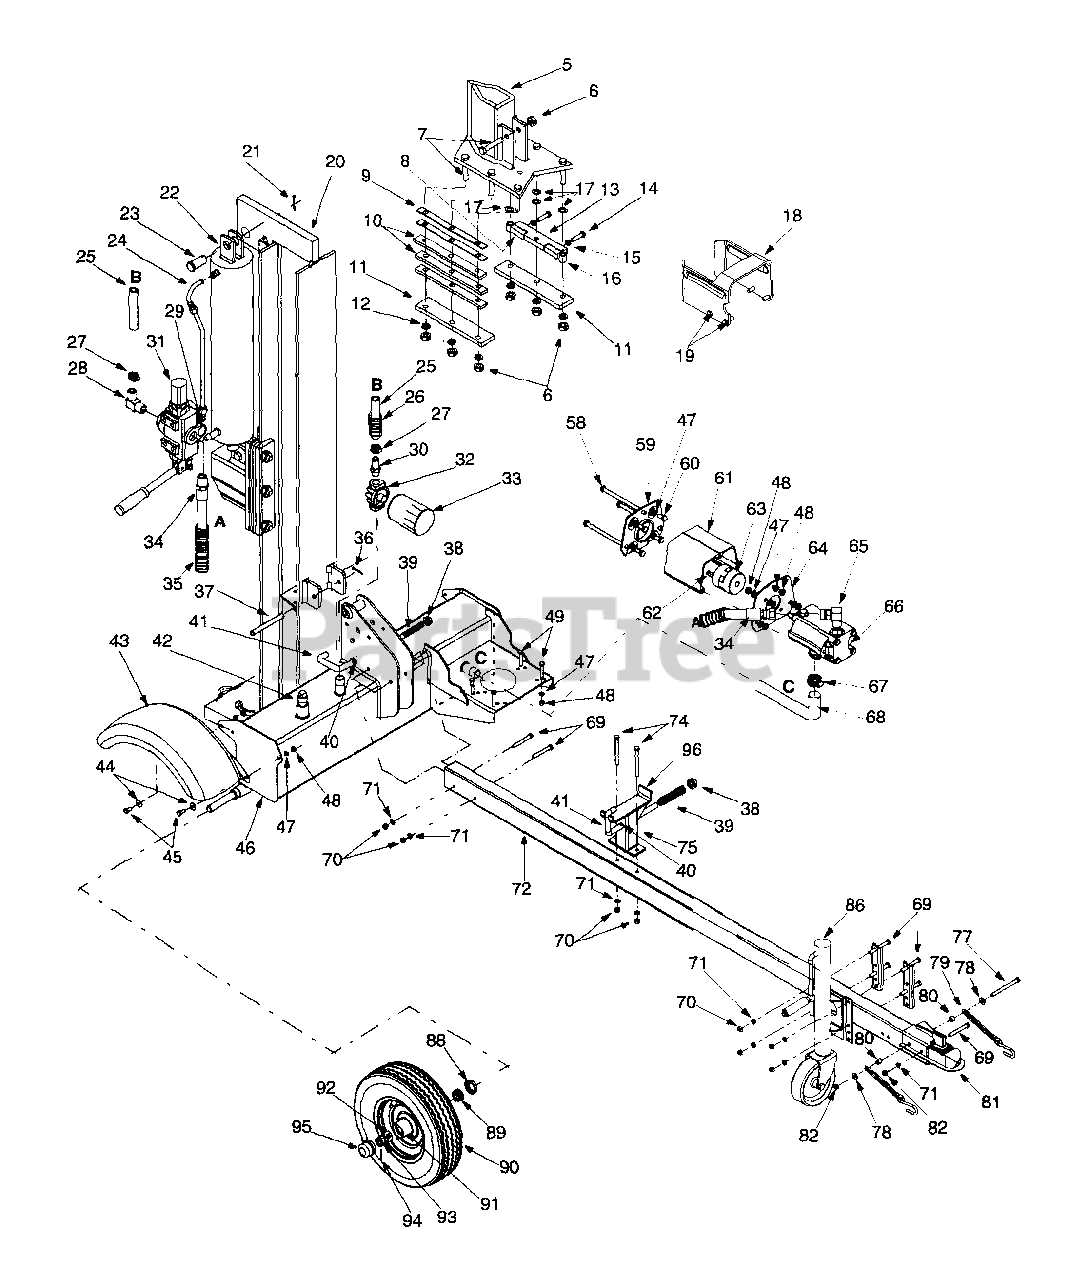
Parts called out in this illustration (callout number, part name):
6	Lock Nut 1/2-20
7	Hex Cap Screw 1/2-20 x 2.75
12	Lock Washer 1/2
14	Hex Cap Screw 3/8-24 x 1.5
15	Hex Jam Nut 3/8-24
16	Spacer
17	Flat Washer.531 x.93 x.090
19	Hex Screw 3/8-16 x 1.0" Gr.5
22	Kit Seal 5.0" for Best Metals cylinder 718-0313
22	Hydraulic Cylinder
22	Kit Seal 5.0" for XINGHUI cylinder 718-0313A
22	Kit Seal 5.0" for ENERGY cylinder 718-0313A
23	Clevis Pin
24	Hydraulic Tube
25	Return Hose 3/4" ID x 44" Lg
26	Hose Guard
27	Hose Clamp 5/8"
28	Return Elbow
29	90 Degree Solid Male Adapter
30	3/4" Hose Adapter
32	Filter Housing
33	Oil Filter
34	High Pressure Hydraulic Hose
35	Hose Guard
36	Cotter Pin 1/8" Dia
37	Hinge Pin 1/2 x 4.8" Lg.
38	Push Cap
39	Comp. Spring 4" Lg.
40	Flat Washer .635 ID x.93 OD
41	Locking Rod
42	Pipe Plug
45	Hex Cap Screw 5/16-24 x.75
48	Hex Nut 5/16-24
49	Hex Cap Screw 5/16-24 x 1.75
58	Hex Screw 5/16-24 x 5.25"
60	Hex Cap Screw 5/16-24
61	Coupling Shield
62	Square Key
63	Flexible Coupling
65	Adapter
66	Gear Pump (16 gpm)
67	Hose Clamp
68	Suction Hose
69	Hex Cap Screw 3/8-16 x 3.0
70	Hex Nut 3/8-16
71	Lock Washer 3/8
74	Hex Cap Screw 3/8-16 x 4.0
77	Hex Cap Screw 3/8-16 x 4.25
78	Flat Washer.385 ID x.870 OD
79	Chain
80	Spacer
81	Hitch Coupler
82	Lock Nut 3/8-16
86	Adjustable Jack Stand
88	Bearing Seal Only
89	Bearing Cone
90	Wheel Asm Comp - Gray
91	Bearing Cup
92	Flat Washer.76" ID x 1.5" OD
93	Slotted Nut 3/4-16
94	Cotter Pin 5/32" x 1-1/4" Lg.
95	Hub Cap
